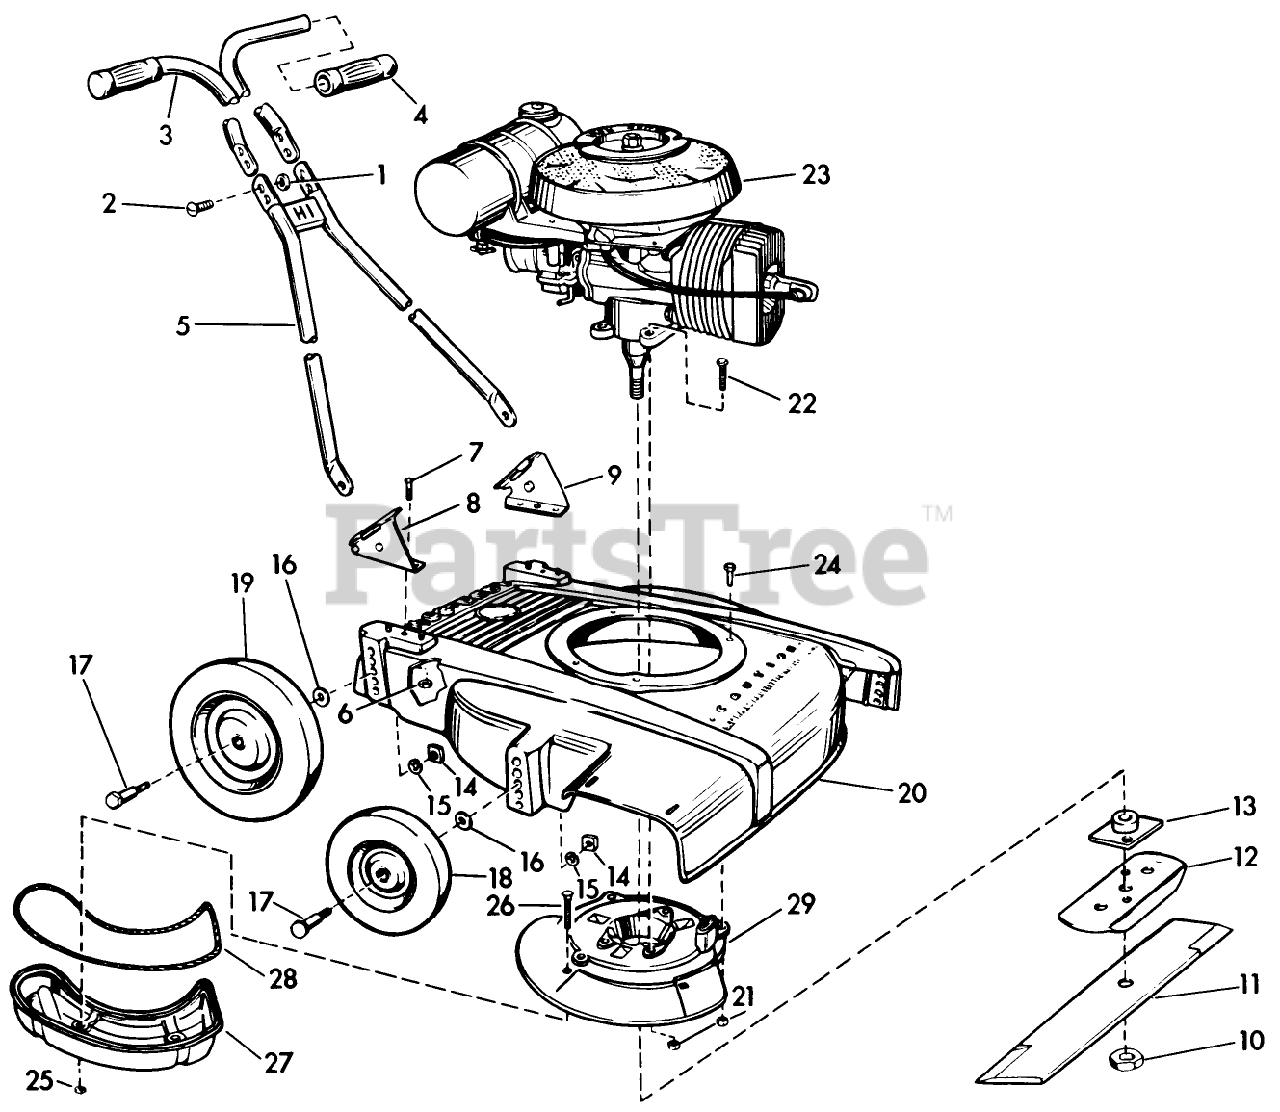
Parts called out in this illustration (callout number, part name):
1	STOP NUT
10	NUT-BLADE
11	Blade-18"
13	Collar and Plate Assembly
15	WASHER, LOCK
20	Housing-18"
25	LOCKNUT E
